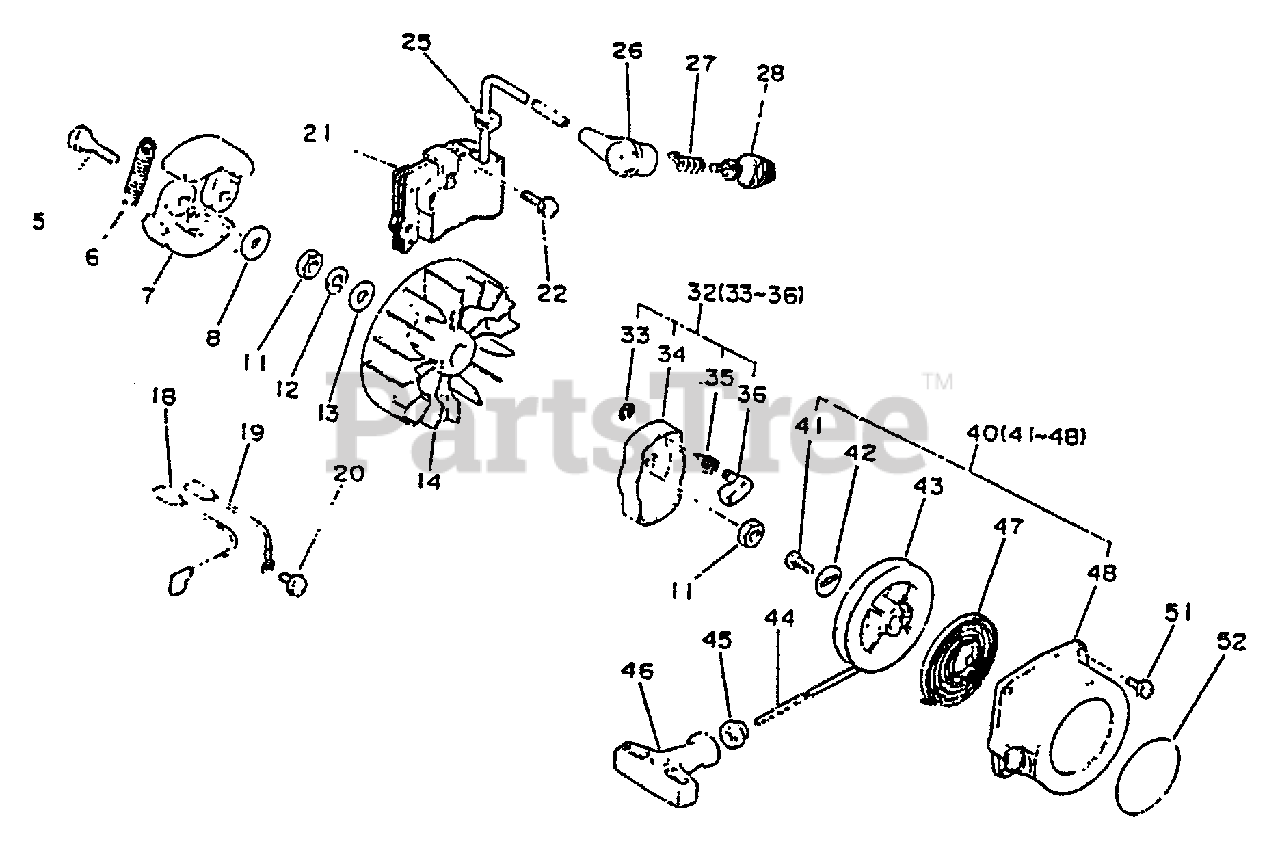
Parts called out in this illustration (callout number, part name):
5	BOLT, CLUTCH
6	SPRING, CLUTCH
7	SHOE, CLUTCH
8	WASHER - 6
12	LOCKWASHER - 8
13	WASHER - 8
14	FLYWHEEL
18	LEAD
19	LEAD - GROUND
20	SCREW - 5X10
21	COIL, IGNITION
22	SCREW - 5X20
26	CAP, SPARK PLUG
27	TERMINAL, SPARK PLUG CAP
28	SPARK PLUG -- BPM-7A
32	STARTER PAWL ASSY
33	RING, RETAINING - 4
34	CATCHER, PAWL
35	SPRING, RETURN
36	PAWL, STARTER
40	STARTER ASSY
42	WASHER
43	REEL, ROPE
44	ROPE, STARTER - 3.5X850
45	GUIDE, ROPE
46	GRIP, STARTER
47	SPRING, REWIND
48	CASE, STARTER
51	SCREW - 4X14
52	LABEL - ECHO
